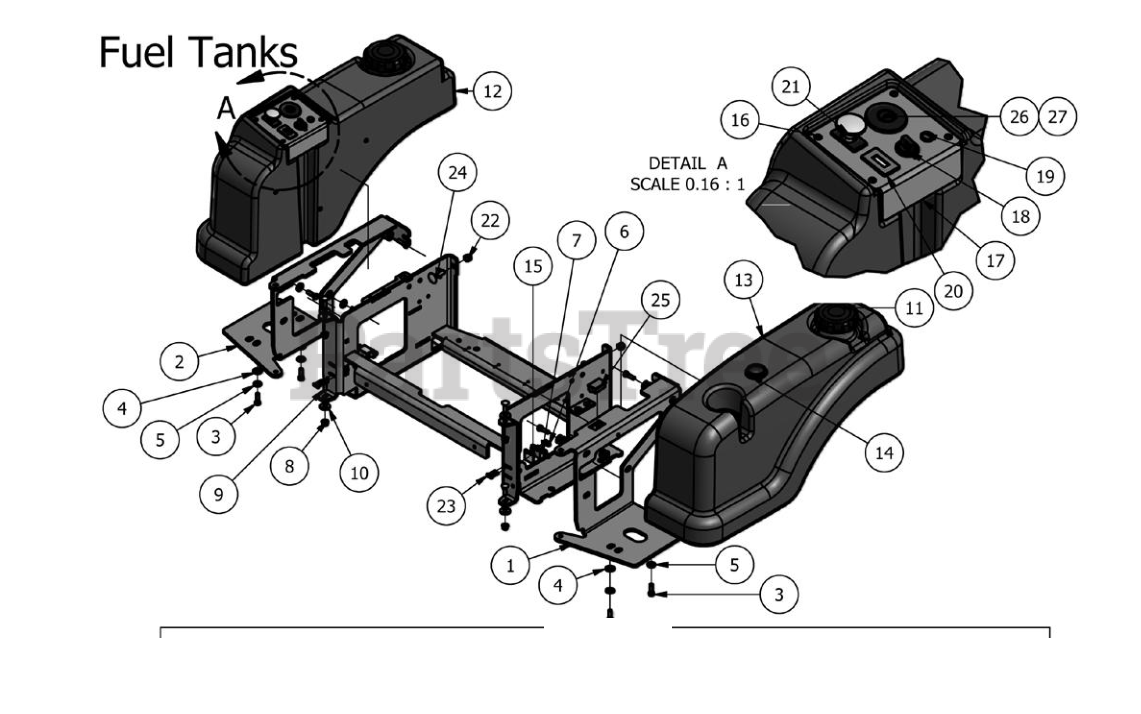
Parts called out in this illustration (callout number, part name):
1	Tank Support-Left
2	Tank Support-Right
3	5/16-18 x 1 Grade 5 Hex bolt Zinc
4	5/16 USS Flat Washer Zinc
5	5/16 Lock Washer Zinc
6	10-24 Nylon Insert Locknut Zinc Orange Nylon
7	Brake Handle Switch
8	5/16-18 Nylon Insert Flange Nut Zinc Orange Nylon
9	5/16-18 x 1 Carriage Bolts Zinc
10	.360ID Plastic Washer
12	Right Tank
14	Fuel Gauge and Grommet
15	Switch Block Plastic
16	10-32 x 3/8 Button Socket C/S 18-8 SS
17	Control Panel
18	12V AUX Connection
20	Tachometer
21	PTO Engager
22	3/8-18 Nylon Insert Locknut Zinc Orange Nylon
23	10-24 x 1 Button Socket C/S 18-8 SS
24	3/8" x 1-1/4" Carriage Bolt
25	Control Panel Stop
26	Ignition Switch
27	Ignition Key
